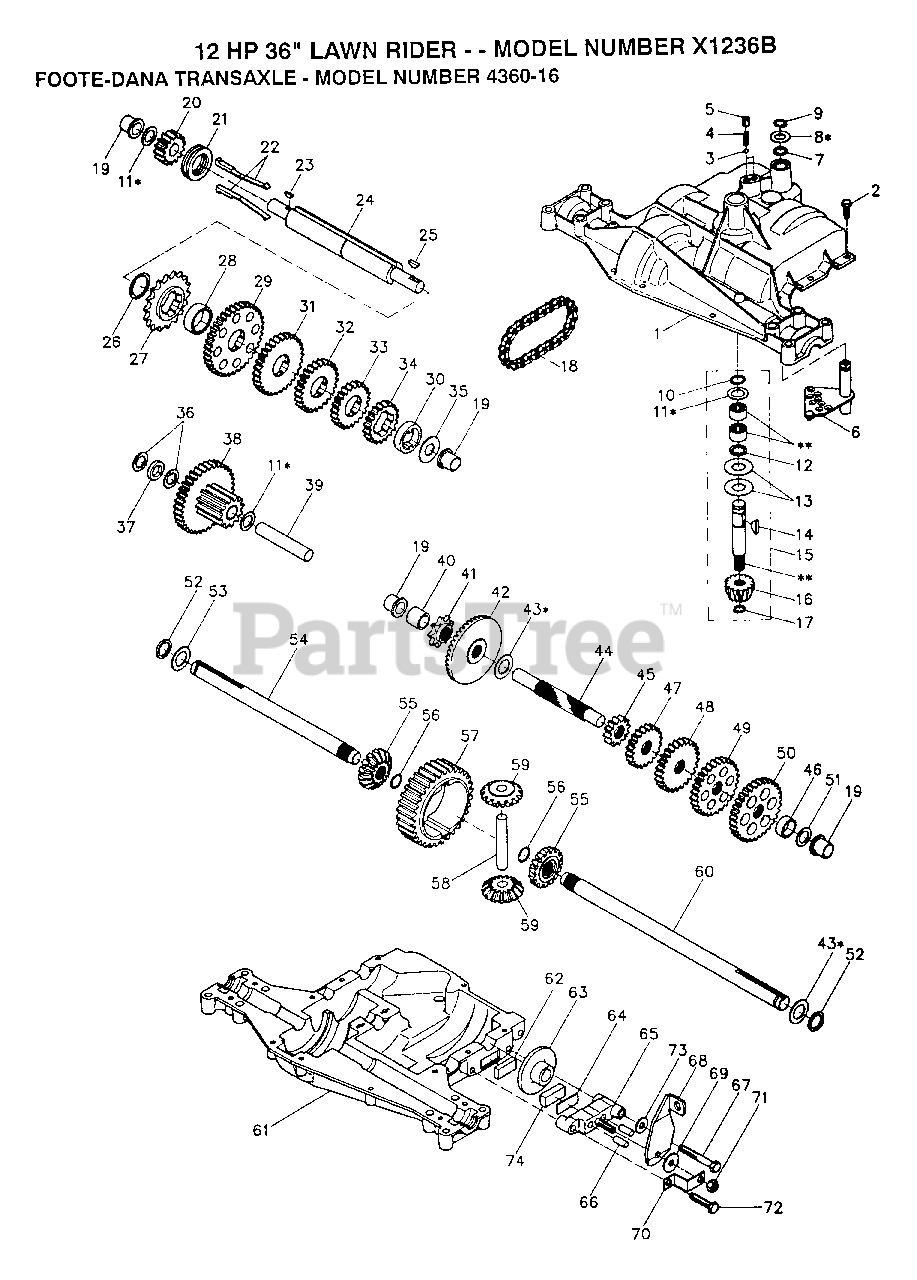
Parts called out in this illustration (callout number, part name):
3	"DETENT, BALL(68003)"
4	"SPRING, DETENT LT"
5	"SCREW, SET LT"
7	ORING T
8A	WASHER T
8B	WASHER T
8C	WASHER T
8D	WASHER T
8E	PLAIN WASHER
8F	WASHER T
9	RETAINING RING LT
10	RETAINING RING LT
11	WASHER
11A	WASHER 020
11B	WASHER 025
11C	WASHER 031
11D	WASHER 035
11E	WASHER 040
11F	WASHER 045
11G	WASHER 050
11H	WASHER 060
11I	"WASHER, PLAIN LT"
13	WASHER T
14	WOODRUFF KEY
15	IMPUT KIT T
16	PINION 14T T
17	"RING,RETAINING LT"
18	"CHAIN,24 PTCH LT"
19	BEARING.FLNG.5510
22	KEY T
25	WOODRUFF KEY
26	"RING,RETAINING LT"
27	SPROCKET 18T T
28	SPACER YT
29	KIT.GEAR.12/37TH
32	GEAR 25T LT
33	GEAR SPUR 22 TT
35	"WASHER, PLAIN LT"
36	WASHER 025
37	SPACER
38	ASSM GEAR COMB
39	SHAFT IDLER T
40	SPACER T
41	SPROCKET 9T LT
43	WASHER LT
43A	"WASHER, PLAIN LT"
43B	"WASHER, PLAIN LT"
43C	"WASHER, PLAIN LT"
43D	WASHER
43E	"WASHER, PLAIN LT"
43F	WASHER 031
43G	"WASHER, PLAIN LT"
43I	WASHER PLAIN
43J	"WASHER, PLAIN LT"
43K	"WASHER, PLAIN LT"
43L	WASHER 062
44	SHAFT T
48	"GEAR, SPUR 25T LT"
49	GEAR 28T T
50	"GEAR, SPUR 31T LT"
51	WASHER 060
53	WASHER 062
55	GEAR 15T T
56	"RING,RETAINING LT"
58	SHAFT T
59	GEAR 1ST T
62	PUCK T
63	BRAKE DISC. T
64	SPACER LT
66	PIN T
67	SCREW T
68	LEVER ACTUATOR
69	WASHER LT
71	NUT.LOCK.5/16-24
72	"SCREW, TAPPING LT"
73	WASHER T
74	PUCK T
